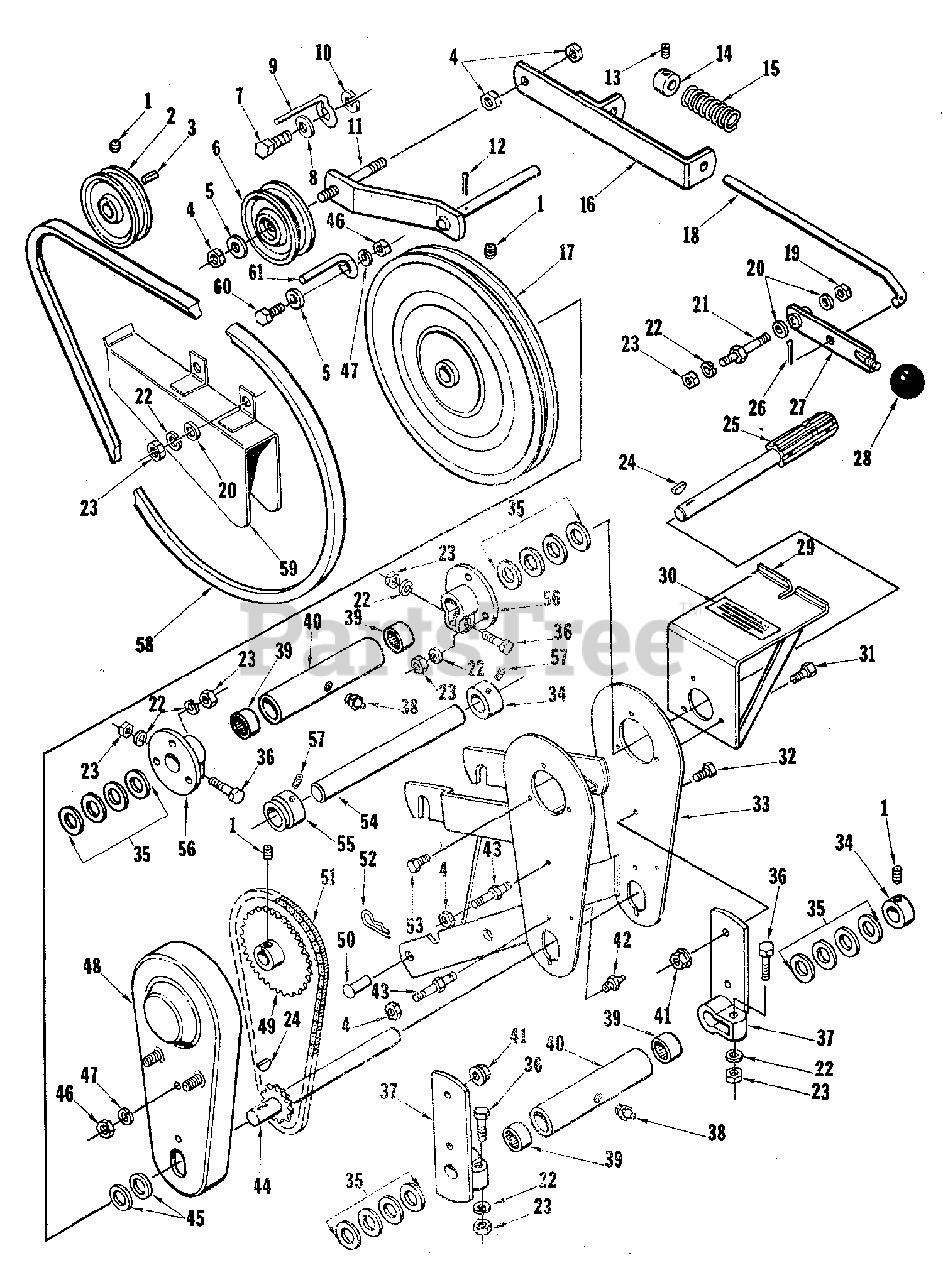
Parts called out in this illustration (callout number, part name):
1	SCREW, Set, 5/16-18 x 5/16
4	NUT, Hex Lock, 3/8-16
5	WASHER, Flat, 3/8
6	PULLEY, Idler
7	SCREW, Cap, 7/16-14 x 1-1/4
8	WASHER, Flat, 7/16
10	WASHER, Lock, 7/16
11	PIVOT ASSEMBLY
12	PIN, Cotter, 1/8 x 1
13	SCREW, Set, 1/4-20 x 3/8"
16	GUIDE ASSEMBLY, Clutch
19	NUT, Hex Lock, 5/16-18
20	WASHER, Flat, 5/16
22	WASHER, Lock, 5/16
23	NUT, Hex, 5/16-18
24	KEY, Woodruff
25	SHAFT ASSEMBLY
26	PIN, Cotter, 3/32 x 5/8
27	HANDLE ASSEMBLY
29	GUARD ASSEMBLY, PTO
30	DECAL, Warning
31	SCREW, Cap, 5/16-18 x 3/4
32	SCREW, Cap, 3/8-16 x 3/4
33	FRAME ASSEMBLY
36	SCREW, Cap, 5/16-18 x 1-1/2
37	SUPPORT ASSEMBLY, Clamp
38	FITTING, Grease
39	BEARING, Needle
40	HOUSING, Bearing
41	NUT, Flange, Hex Lock, 3/8-16
42	FITTING, Grease
44	SHAFT ASSEMBLY
46	NUT, Hex, 3/8-16
47	WASHER, Lock, 3/8
48	GUARD ASSEMBLY, Chain
49	SPROCKET ASSEMBLY
51	CHAIN, W/Connector Link
53	SCREW, Cap, 5/16-18 x 5/8
56	FLANGE ASSEMBLY
59	GUARD ASSEMBLY, Belt
60	SCREW, Cap, 3/8-16 x 1
